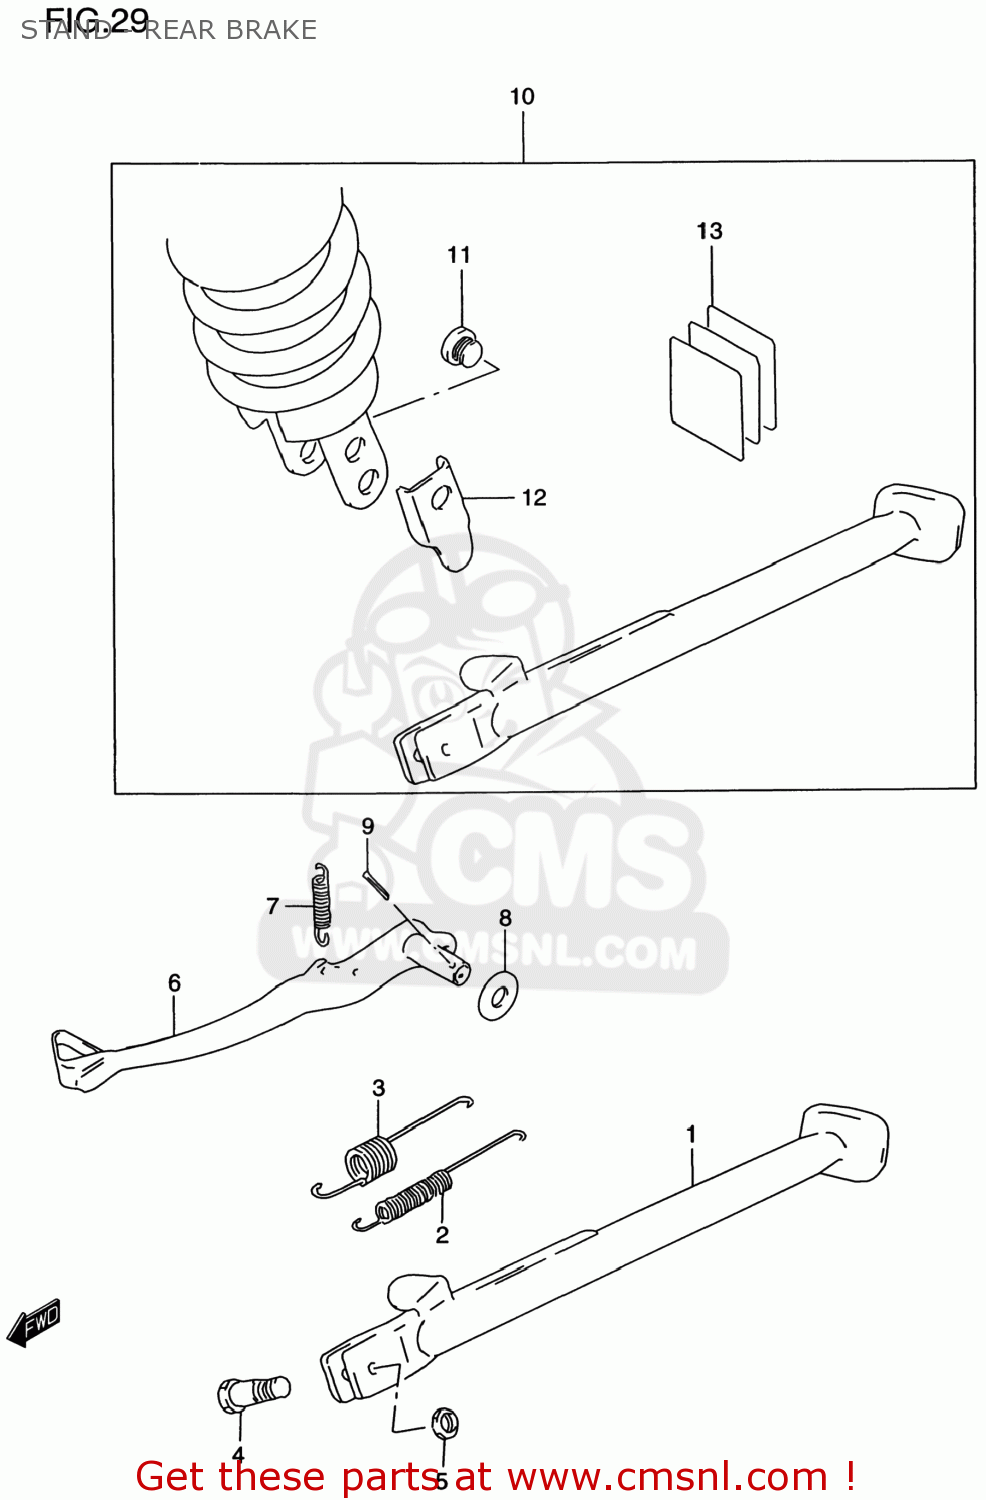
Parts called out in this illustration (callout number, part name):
1	STAND,PROP
2	SPRING
3	SPRING
4	BOLT(10X30)
5	NUT
6	PEDAL,BRAKE
7	SPRING
8	WASHER(15.5X26X2.3)
9	COTTER PIN
10	Low Side Stand
11	PLUG
12	PLATE,RR SHOCK ABSORBER LWR
13	LABEL SET,WARNING
